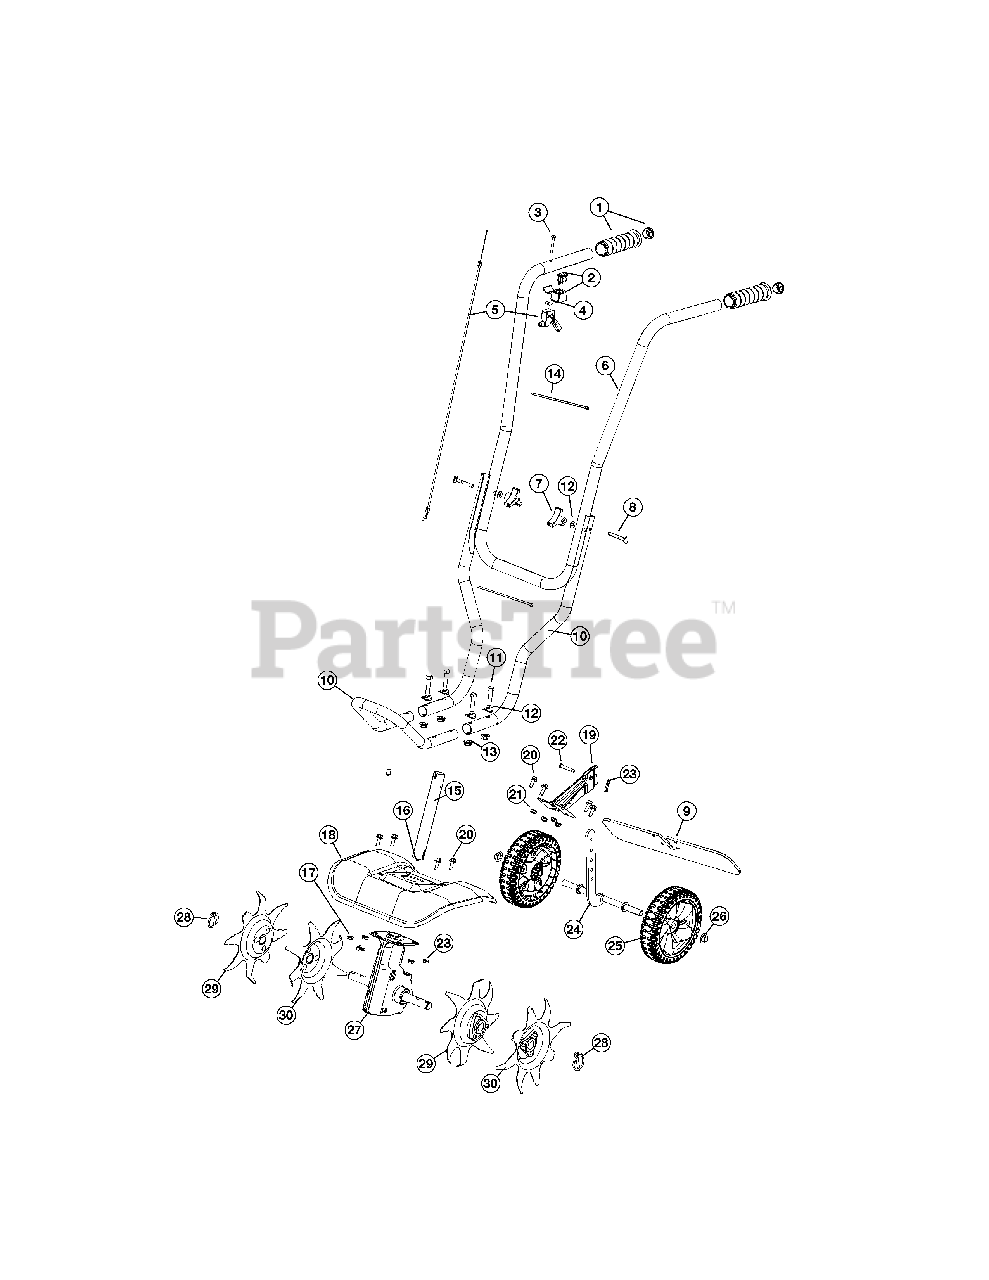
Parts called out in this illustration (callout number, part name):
2	Switch Assembly
3	Screw
5	Throttle Assembly
6	Upper Handle
9	Debris Shield
10	Lower Handle Assembly
11	Bolt
12	Washer
14	Cable Tie
15	Boom Assembly (Incl. 16)
16	Flex Shaft
17	Bolt
18	Tine Shield
19	Wheel Bracket Assembly
22	Clevis Pin
23	Cotter Pin
24	Wheel Support Bracket
29	Tine (RH Outer/ LH Inner)
30	Tine (LH Outer/ RH Inner)
